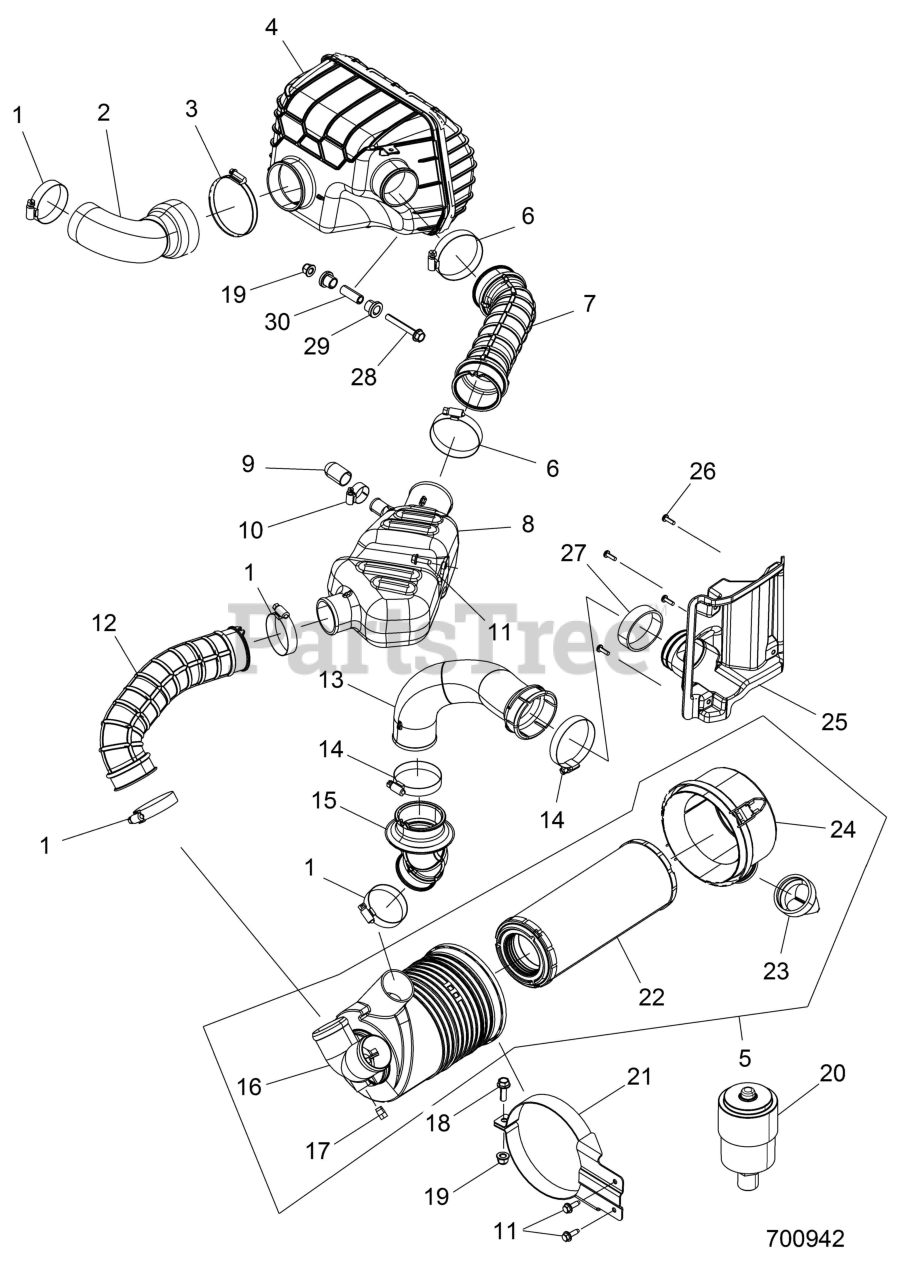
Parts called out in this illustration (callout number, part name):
1	CLAMP, HOSE, S.S.(10)
2	HOSE-INTAKE,ENG,DSL
3	CLAMP-BAND,NARROW 70-90MM
4	WELD-INTAKE,PLENUM
5	ASM., AIR INTAKE
6	CLAMP-HOSE, 2.75"-SS
7	HOSE, ENGINE INTAKE
8	DUCT-INTAKE,ENG
9	CAP, RUBBER, .75 ID X 1.00
10	CLAMP, SPRING BAND 26/12
11	SCR-M6X1.0X20,HXHD,FLG,TDFM,BL
12	HOSE-AIR BOX,SPLY
13	DUCT-INTAKE,AIR
14	CLAMP, HOSE
15	HOSE-INTAKE,AIR BOX,SPLY
16	ASM., AIRBOX, MAIN
17	PLUG-AIRBOX
18	BOLT-M8X1.25X25,HXFLG-OLIVE D
19	NUT-M8X1.25,FLG,NYLOC-OLIVE D
20	KIT, FILTER, INDICATOR
21	WELD-AIRBOX,MOUNT
23	VALVE-AIRBOX
24	ASM-LID,AIRBOX
25	INTAKE-FENDER,REAR,BLK
26	SCR-10X5/8-HI/LO,PN-T25,TRX-M
27	HOSE-INTAKE,BOOT
28	SCR-HXFL-M8X1.25X60 8.8 ZOD
29	BUSHING-MOUNT
30	SHAFT-COMPRESSION LMTR,34.4MM
